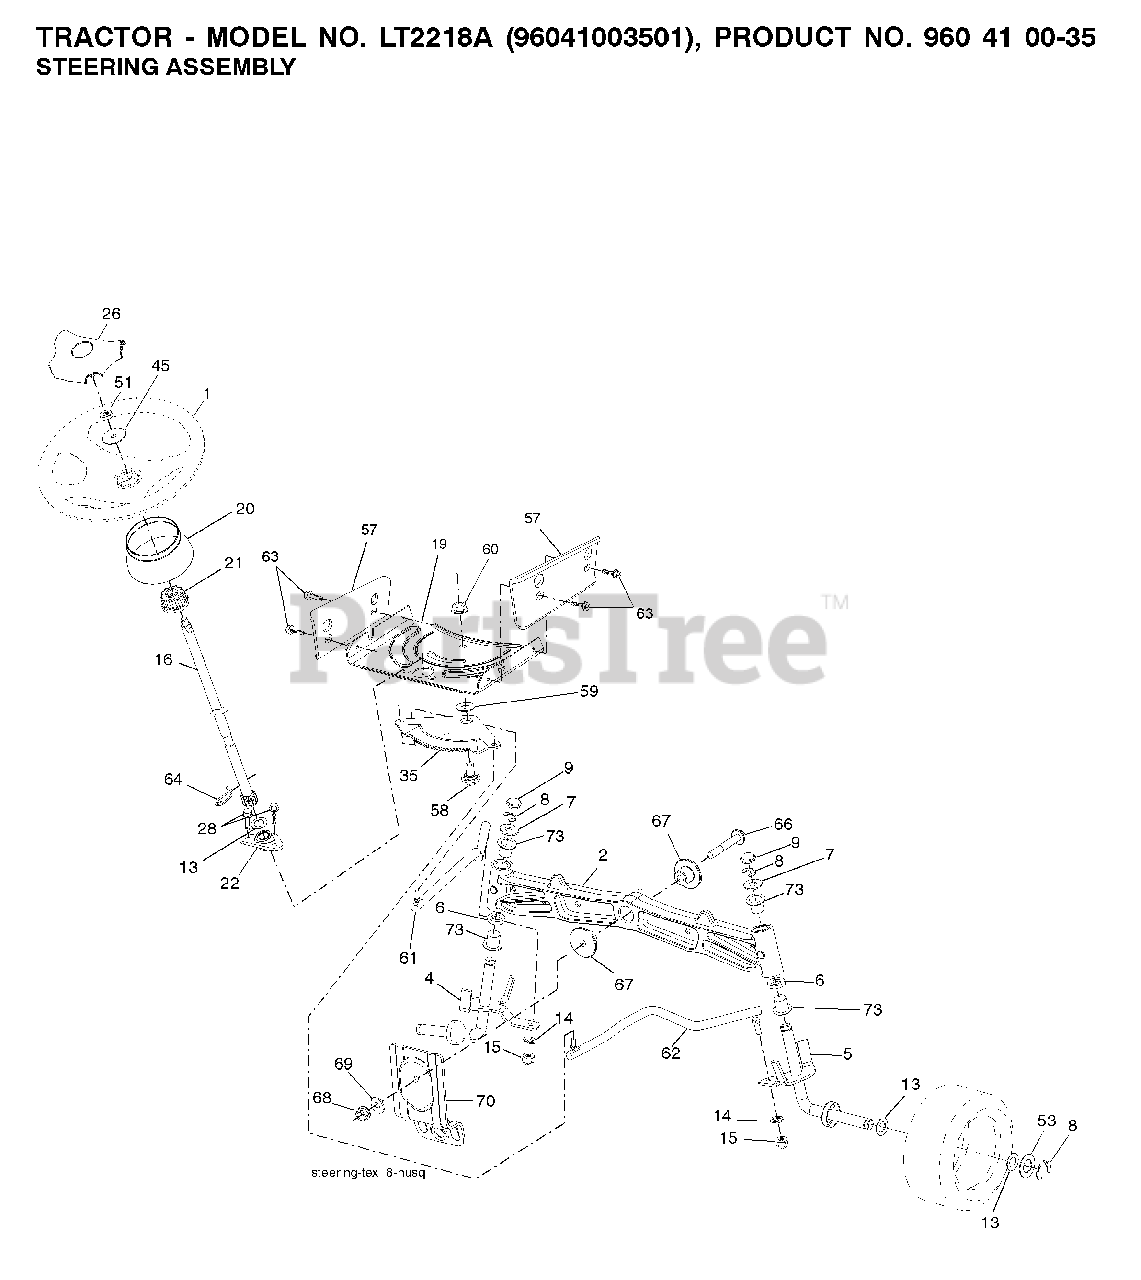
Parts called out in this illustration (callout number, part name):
1	WHEEL.STEERING.PREM.2.BLK
2	AXLE.HALF.ASM.WELDED
4	SPINDLE.WELDED.LH.15"TEX
5	SPINDLE.WELDED.RH.15"T
8	RING CLIP
9	CAP.SPINDLE
14	WASHER, LOCK 3/8
15	NUT CROWNLOCK 3/8-24
16	SHAFT.STEER.STEALTH.DD
19	PLATE.STEER.DDL.NLT/NG
20	BOOT.STEERING.
21	ADAPTER, WHEEL STNG..
22	BUSHING.ASM.STEERING.A
26	INSERT.CAP.STRG.WH.BLACK
28	SCREW, 3/8-16X3/4
35	GEAR.SECTOR.PLATE.DDL.
45	WASHER.11/32
51	NUT.HEX.1/2-20
53	WASHER.HARDENED
57	BRACKET.UPSTOP.TEX
58	BOLT.SHOULDER.SECTOR.P
59	WASHER.THURST.SECTOR.S
60	NUT FLANGE LOCK 5/8-11
61	DRAGLINK.LH.BALLSTUD.D
62	DRAGLINK.RH.BALLSTUD.D
63	SCREW
64	RETAINER.CLIP.SPRING.S
66	BOLT HEX FGHD 7/16-14 X 3 SERR
67	BUSHING.PM.FRONT AXLE
68	NUT.LOCK.FLANGE.7/16
69	WASHER.1.5X.505X.118
70	BRKT.DECK.SUSPENSION.F
73	BRNG T
